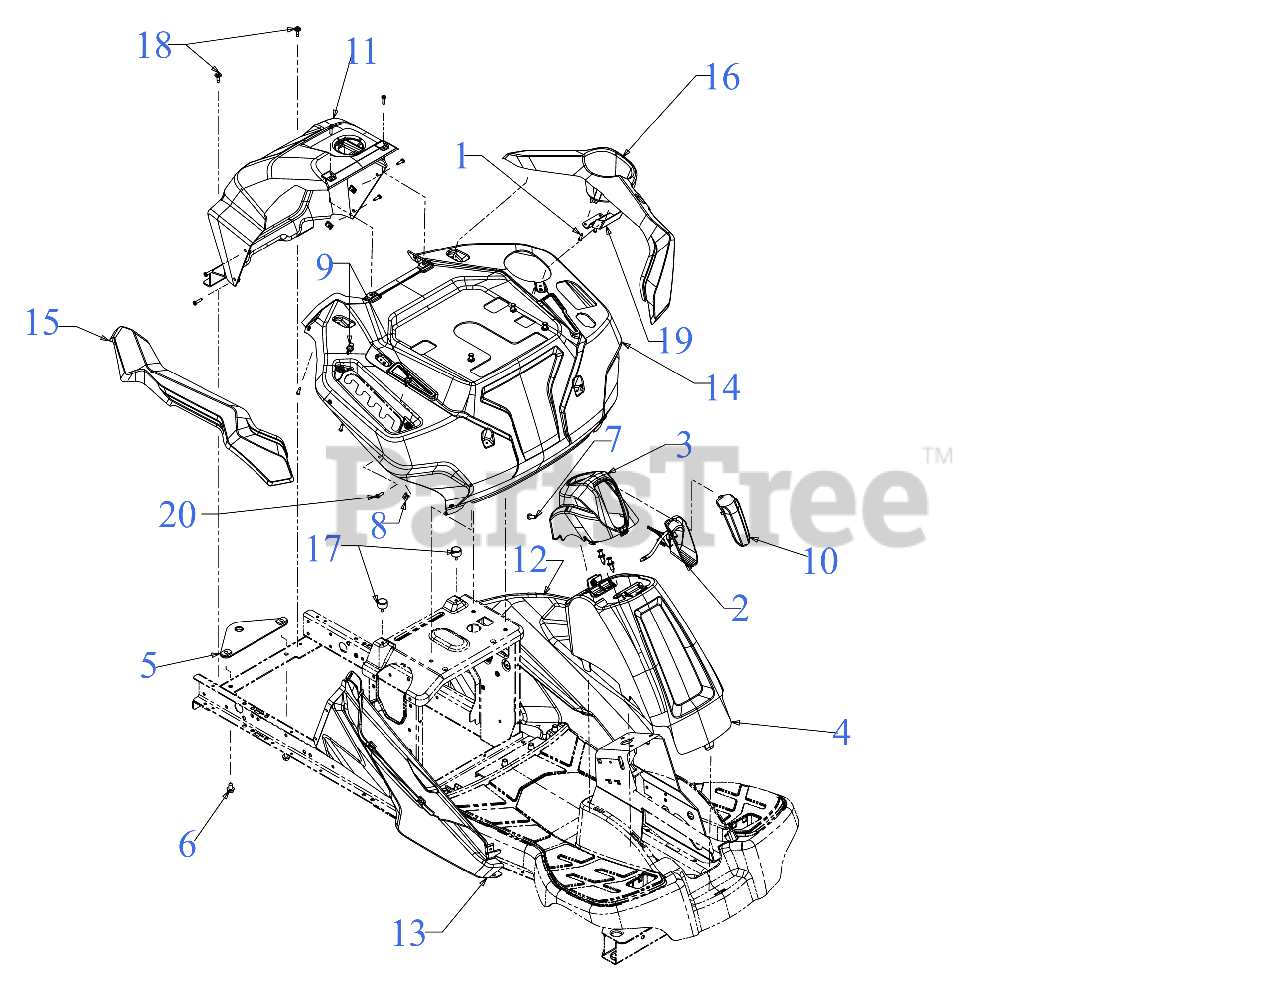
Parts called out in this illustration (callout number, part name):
1	SCREW, #8-16X.750 PH
2	LED HEADLIGHT HARNESS ASSEMBLY
3	COLUMN CAP
4	COLUMN COVER
6	SCREW 5/16-18 x .625
7	SCREW 1/4-20X.75
8	U-NUT #10-16
9	PLASTIC RIVET
10	LED HEADLIGHT LENS
11	REAR BODY COVER
12	BODY PANEL (LH)
13	BODY PANEL (RH)
15	FENDER TRIM (RH) (CUB YELLOW)
16	FENDER TRIM (LH) (CUB YELLOW)
17	BUMPER .62 DIA x .50
18	SHOULDER SCREW M6-1 .368 X.115
19	FENDER BRACKET
20	SCREW:10-6 x .75
